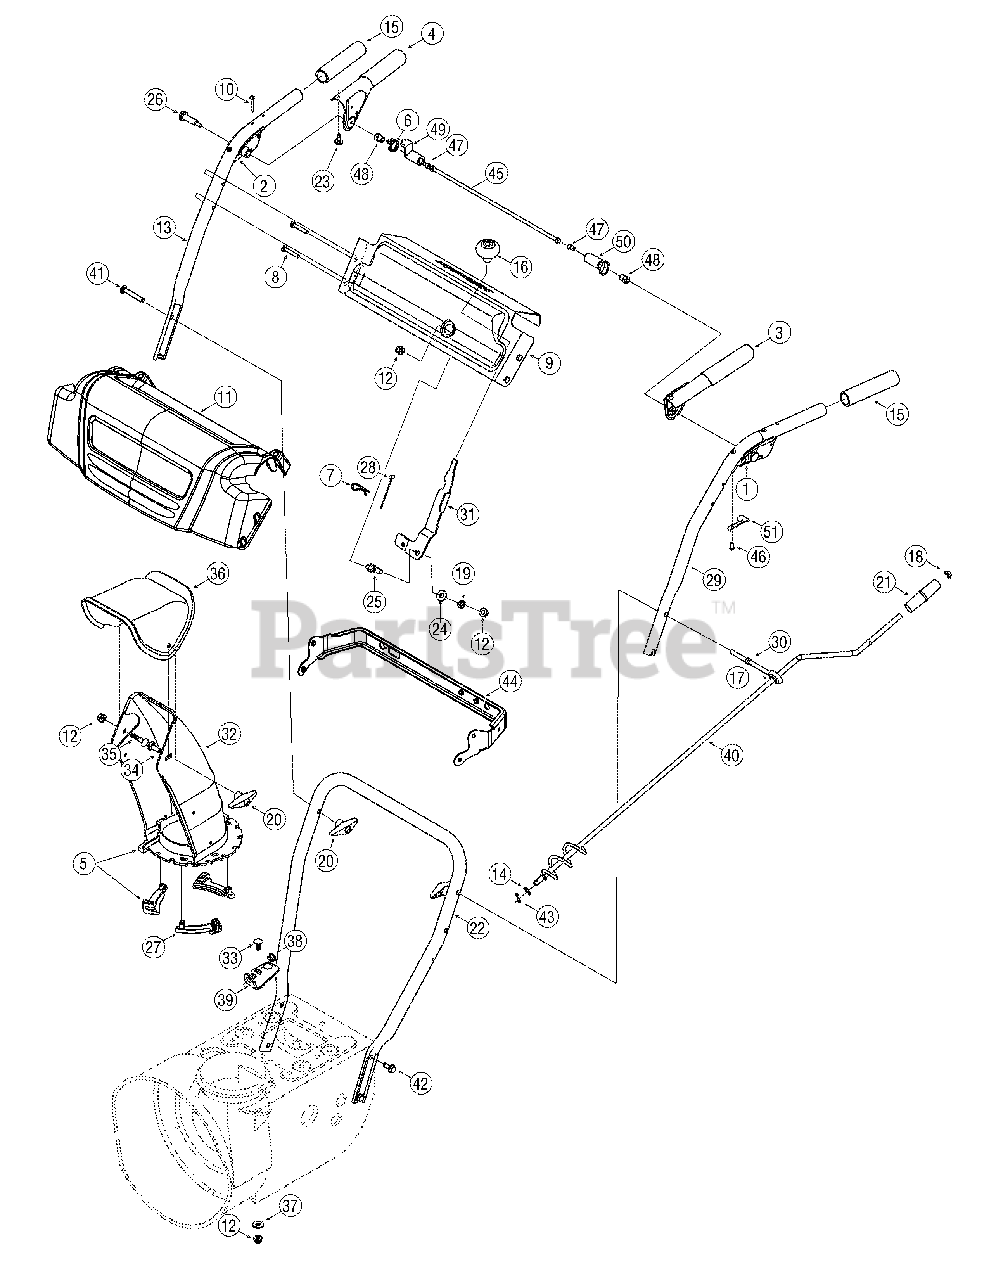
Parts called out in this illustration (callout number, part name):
1	Handle Assembly, Clutch Lock, LH
2	Handle Assembly, Clutch Lock, RH
3	Handle Ass’y, Engage, Red, LH
4	Handle Ass’y, Engage, Red, RH
5	Chute, Lower (Incl. Ref. # 27, Qty. 3)
6	Spring, Torsion, .8156 ID x .3038
7	Click Pin
8	Screw, 1/4-20 x 1.625
9	Panel, Handle, (no cutout)
10	Screw, Machine, #10-24, 1.375
11	Handle Panel Cover
12	Nut, Flange Lock, 5/16-18, Nylon
13	Handle, Upper, RH
14	Washer, Flat, .375 x .738 x .063
15	Grip, 1.0 ID x 5.0
16	Knob, Shift, Black
17	Grommet, .44 ID x .94 OD x .50
18	Cap, Push, 3/8 Rod
19	Spring, .39 x .60 x .88
20	Knob, 5/16-18, Black
21	Crank Knob, 1.0 Dia. x 3.2, Black
22	Handle, Lower
23	Bumper, Rubber, .62 OD x .22
24	Washer, Flat, .385 x .870 x .092
25	Bolt, Shoulder, 5/16-18 x 0.905
26	Screw, Shoulder, .43 x 1.3, 1/4-20
27	Chute, Flange Keeper
28	Cable, Speed Selector
29	Handle, Upper, LH
30	Eye Bolt, Chute Crank
31	Shift Lever
32	Chute, Lower, 5.0 Dia.
33	Bolt, Carriage, 5/16-18, 1.0
34	Bolt, Carriage, 5/16-18, 1.0
35	Bolt, Carriage, 5/16-18, .750
36	Chute, Upper, w/ Label
37	Washer, .349 x .879 x .063
38	Bushing, Plastic, .380
39	Bracket, Chute Crank
40	Crank Assembly, Chute
41	Screw, Carriage, 5/16-18, 2.25
42	Screw, 5/16-18, 2.25, Gr5
43	Pin, Cotter, .072 x 1.13
44	Bracket., Panel
45	Rod Assm., Pivot Lock
46	Screw., #8-16 x .50
47	Screw., 1/4-20 x .50
48	Nut, Hex, 1/4-20
49	Plate., Lock
50	Cam, Clutch Lock
51	Spring, Lock Clutch
